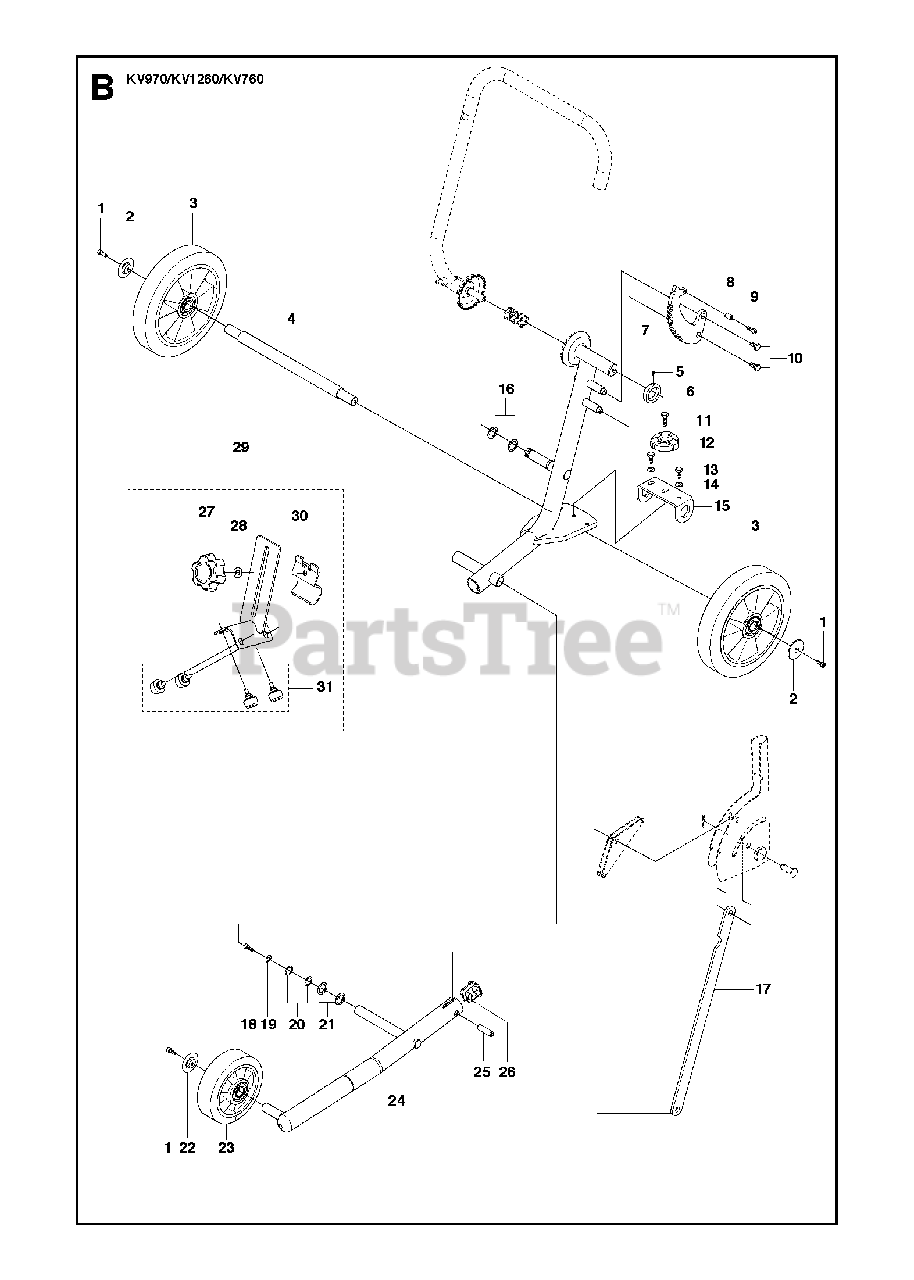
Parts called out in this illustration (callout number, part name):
9	SCREW IHSCM
12	TURNING KNOB
13	SCREW EHHM
28	WASHER
31	BUFFERQty in package: 4 pieces
